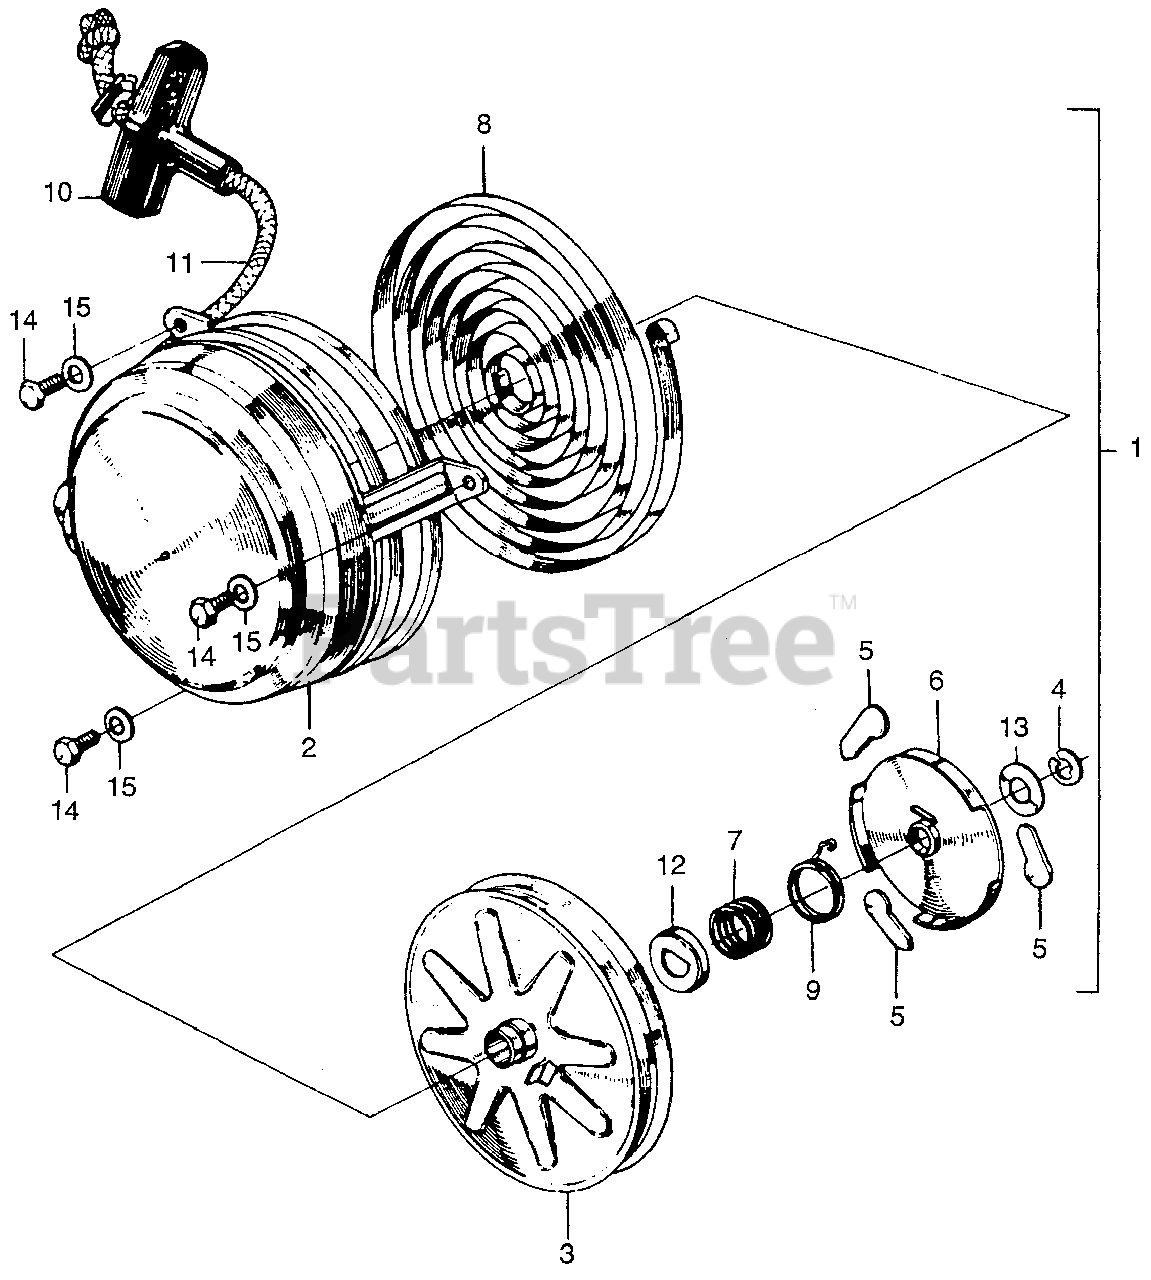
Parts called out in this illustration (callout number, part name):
1	STARTER ASSY., RECOIL *R8* (BRIGHT RED) (NOT AVAILABLE)
2	CASE, RECOIL STARTER *R8* (BRIGHT RED)
3	PULLEY, RECOIL STARTER (NOT AVAILABLE)
5	RATCHET, STARTER
6	PLATE, FRICTION
7	SPRING, FRICTION
8	SPRING, STARTER RETURN
9	SPRING SET
10	KNOB SET, STARTER
11	ROPE, STARTER (#6X64")
14	BOLT, HEX. (6X12)
15	WASHER, PLAIN (6MM)
